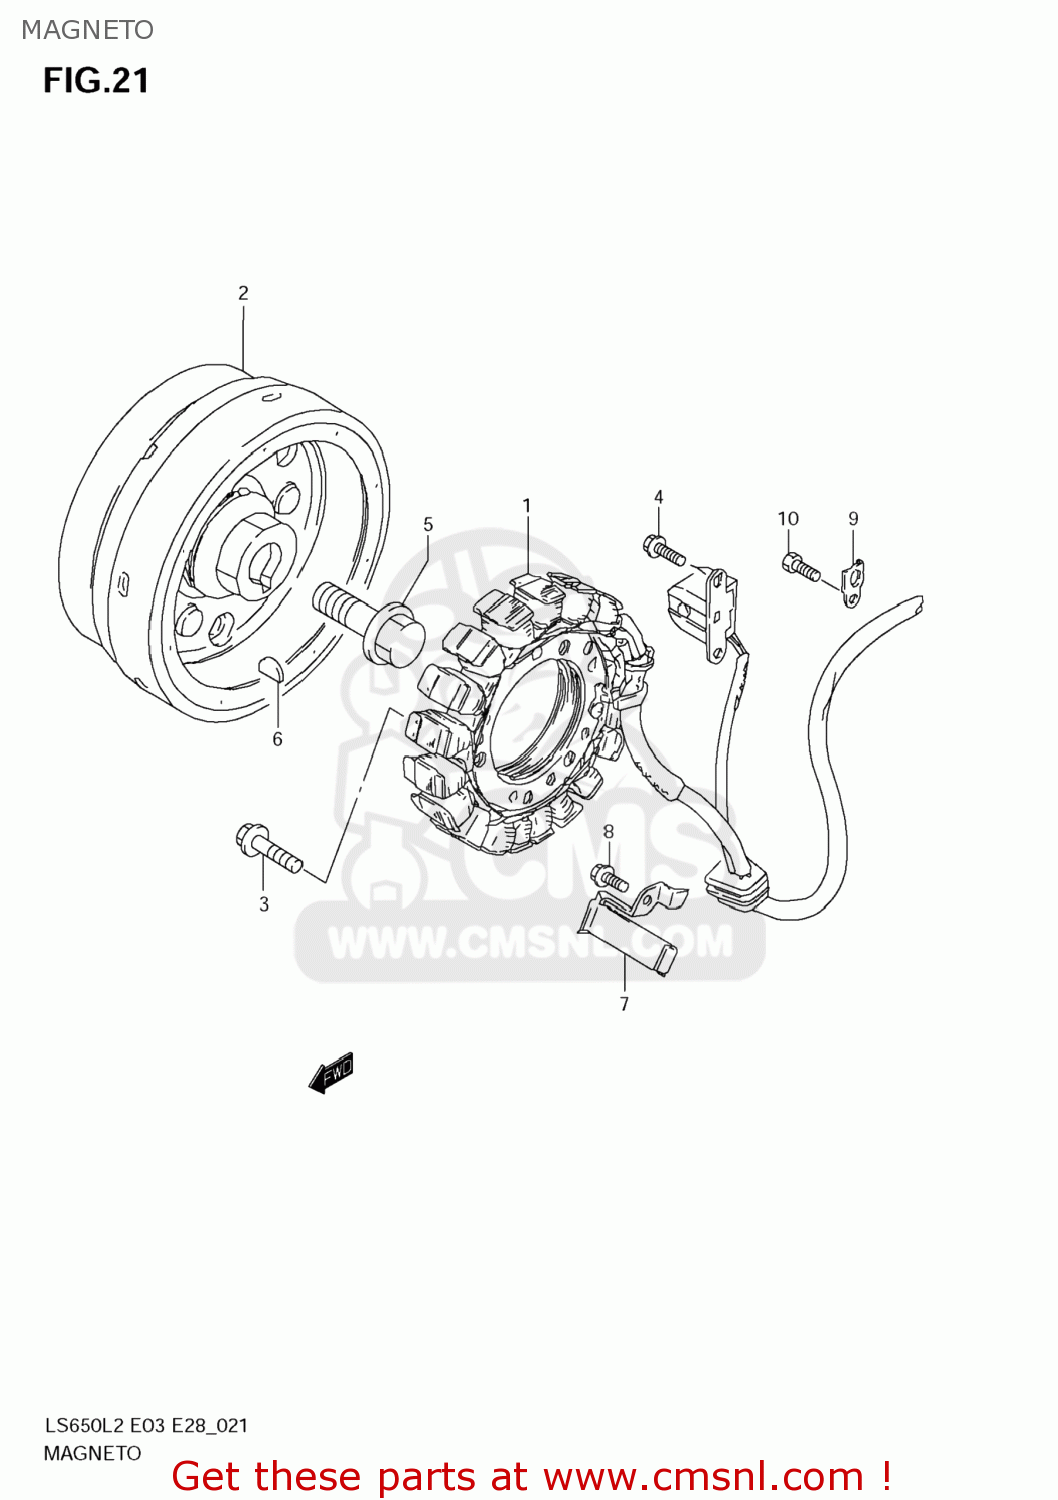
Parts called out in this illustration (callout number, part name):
1	STARTER ASSY
2	ROTOR ASSY
3	BOLT
4	BOLT
5	BOLT(14X43)
6	KEY
7	CLAMP,MAGNETO LEAD WIRE NO.1
8	BOLT
9	CLAMP,GENERATOR LEAD WIRE
10	BOLT(5X10)
